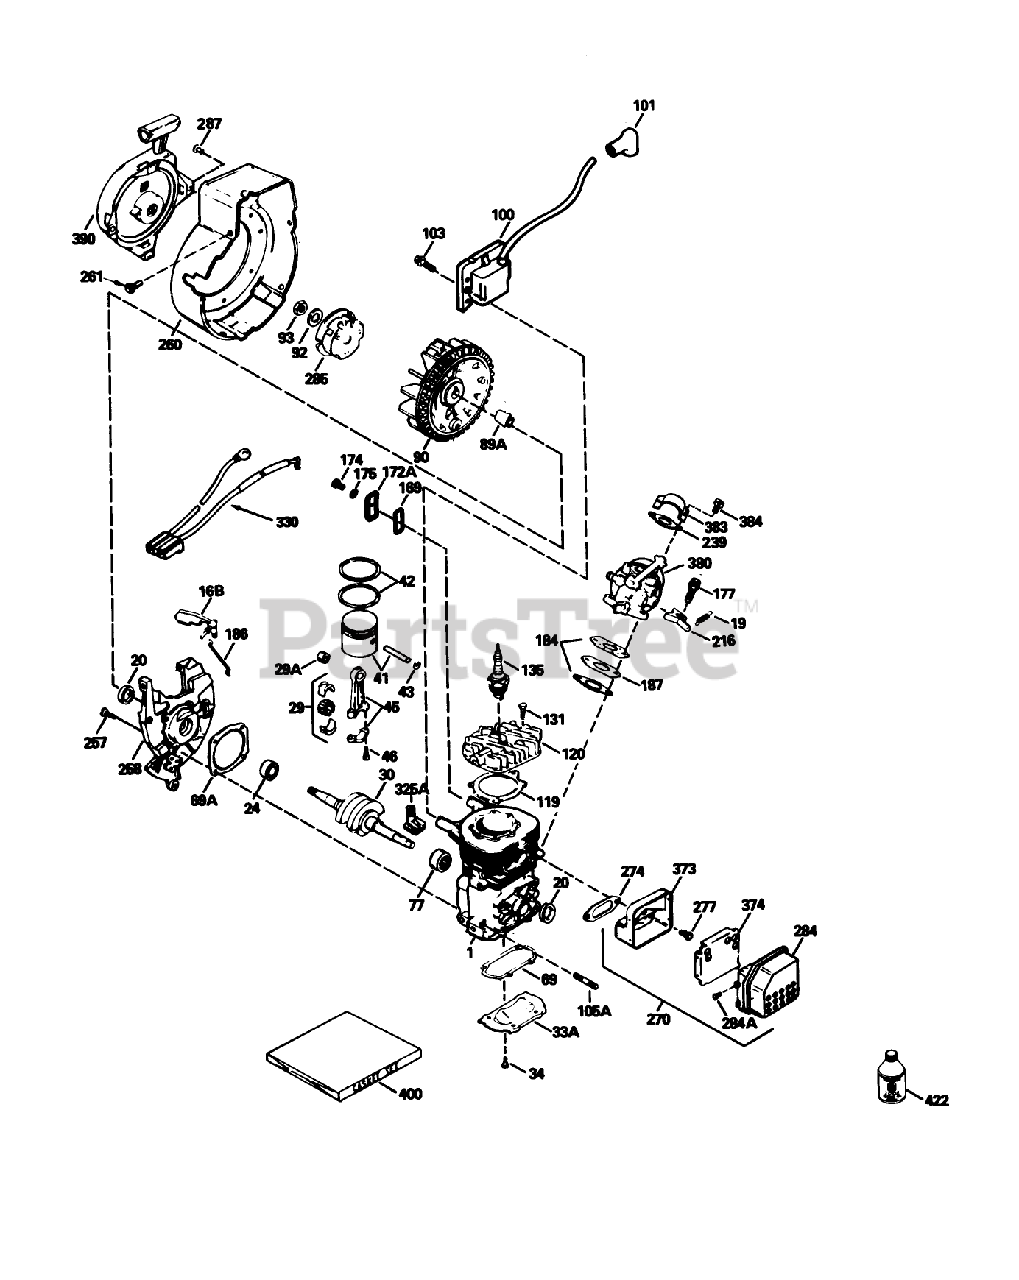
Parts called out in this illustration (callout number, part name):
1	Block Ass-y-Cylinder (Order short block if replacement is required)
16B	Vane-Air
19	Spring-Governor
20	Seal-Oil
24	Bearing-Ball
29	Needle Bearing and Liner Set (37 Needles)
29A	Bearing-Cartridge
30	Crankshaft
33A	Plate-Cover
34	Screw (T-25, 10-24 x 1/2)
41	Piston (Incl. Ref. #43)
42	Ring Set
43	Ring-Retaning
45	Rod Assy.-Connecting (Incl. Ref. #3, 3A 3B)
46	Bolt-Rod, Connecting
69	Gasket-Plate, Cover
69A	Gasket-Cover, Cylinder
77	Bearing-Cartridge
89A	Blade (20 inch)
90	CARB BODY S
92	Washer-Belleville
93	Nut-Flywheel
100	Solid State
101	Cover-Spark Plug
103	Screw
119	Gasket-Head, Cylinder
120	Head-Cylinder
131	Screw (T-30, 1/4-20 x 3/4)
135	Spark Plug-Resistor (R C J 8Y)
169	Cover-Compression, Release
172A	Comp. Release Cover
174	Screw (T-25, 10-24 x 1/2)
175	Washer
177	Screw (5/32 Allen, 1/4-20 x 1)
184	Gasket-Carburetor
186	Link-Governor
187	Spacer
216	Lever-Adjusting, Rpm
239	2060A77 WIZARD ROTA
257	Screw (T-30, 1/4-20 x 5/8)
258	Base Ass-y-Blower Housing (Incl Ref. #20)
260	Housing-Blower
261	Screw (1/4-20 x 1/2)
270	Muffler Assembly (Incl. Ref. #53-57)
274	Gasket-Exhaust
277	Screw (T-30, 1/4-20 x 5/8)
284	Cover Muffler
284A	Screw
285	Cup-Starter
287	Rivet-Pop
325A	Clip-Wire
330A	Harness-Wire
373	Base-Muffler
374	Baffle-Muffler
380	Carburetor (Incl. Ref. #184A)
383	Baffle-Carburetor
384	Screw
390	Starter-Rewind
400	Gasket Set
422	Oil-(2 Cycle) (8 Ounce)
